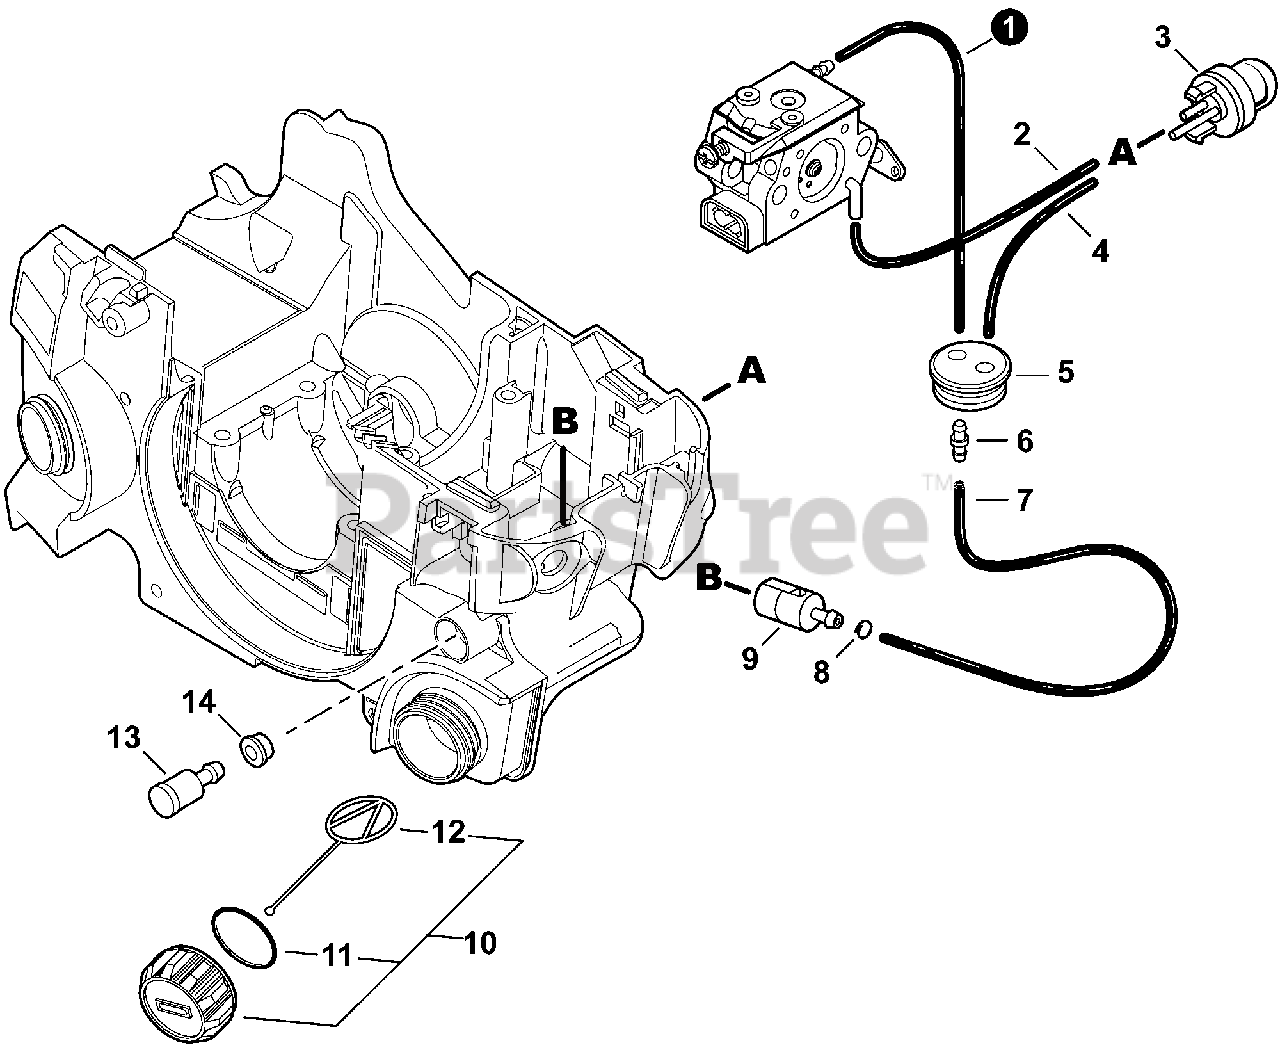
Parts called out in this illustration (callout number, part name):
1	PIPE, FUEL 3×5×85 BLACK
2	PIPE 2.4×5×150 BLACK
3	BULB, PURGE
4	PIPE, FUEL RETURN 2.4×5×80 BLACK
5	GROMMET, FUEL
6	CONNECTOR, PIPE
7	PIPE, FUEL 3×5×144 BLACK
8	CLIP Ø6
9	FILTER, FUEL
10	CAP ASSY, FUEL
11	O-RING 22
12	CONNECTOR, CAP L= 60mm
13	VENT ASSY
14	GROMMET, FUEL
